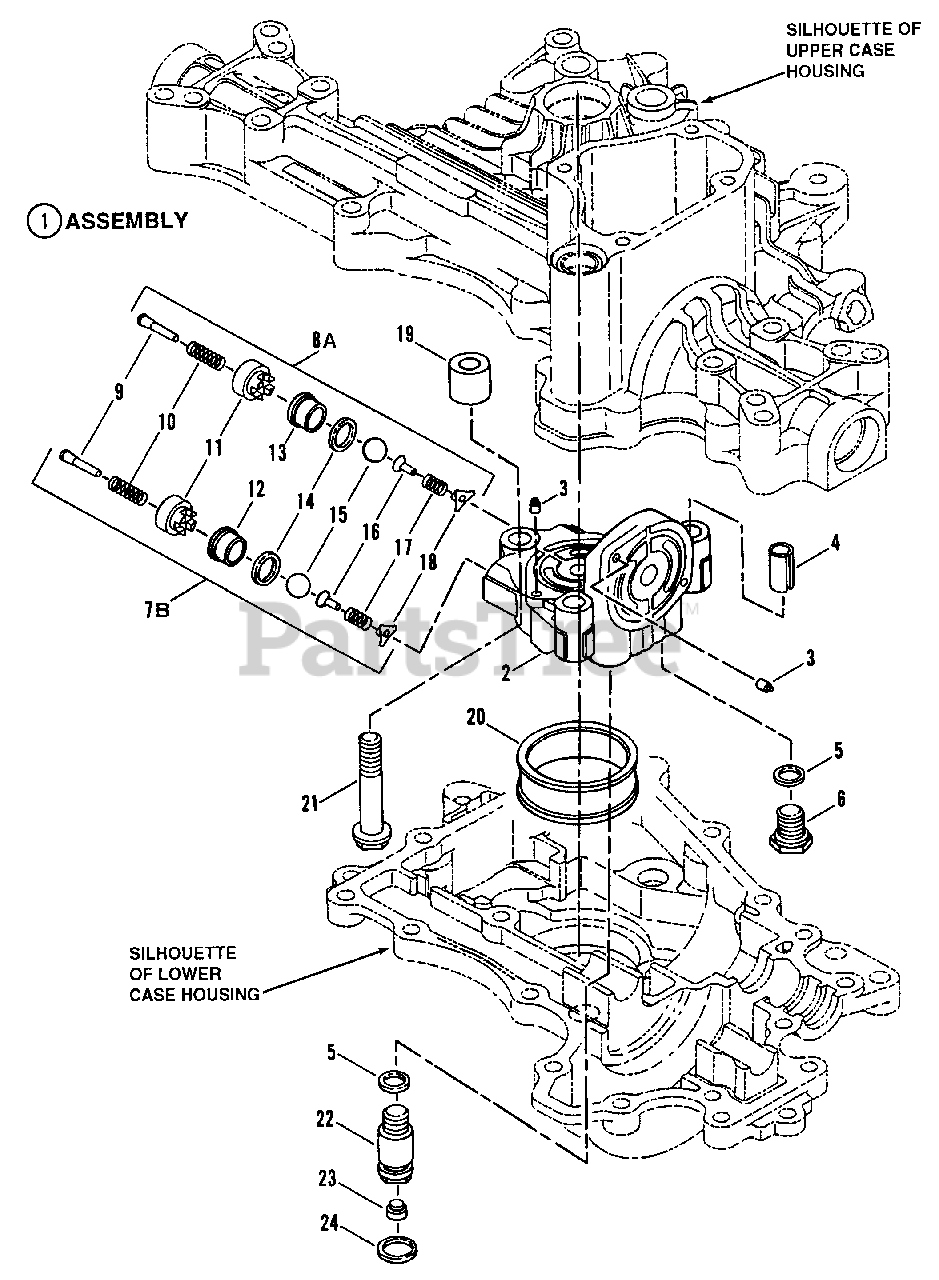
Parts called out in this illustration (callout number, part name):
1	ASSEMBLY, Center Block, Pump & Motor
2	CENTER BLOCK, Pump & Motor
3	PIN, Dowel
4	ROLL-PIN, M12 x 22mm
6	PLUG, Pump Port
7B	VALVE "B", Set
8A	VALVE "A", Set
9	PUSH-PIN, Transport By-Pass Valve
10	SPRING, Push-Pin
11	GUIDE, Push-Pin
12	SLEEVE
13	SLEEVE
14	O-RING
15	BALL
16	HOLDER, Ball
17	SPRING, Holder
18	HOLDER, Spring
19	SPACER, M10 x 20 x 20mm
20	FILTER, Pump
21	CAPSCREW, M10 x 60mm
22	CONNECTOR, Bleed Port
23	PLUG, Pipe
